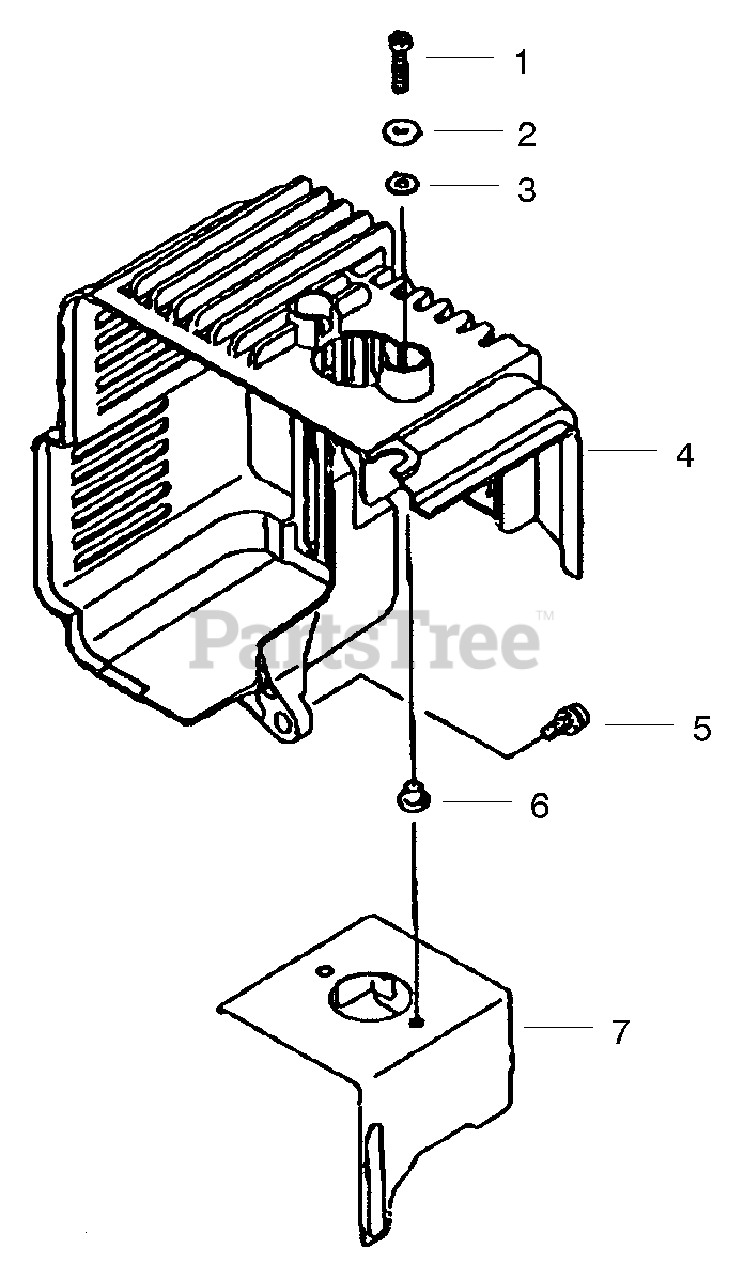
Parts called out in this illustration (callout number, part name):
1	Bolt-5x20
2	Washer-5.5x13.8x2
4	Shroud-Engine
6	Insulator
7	Shroud-Engine
